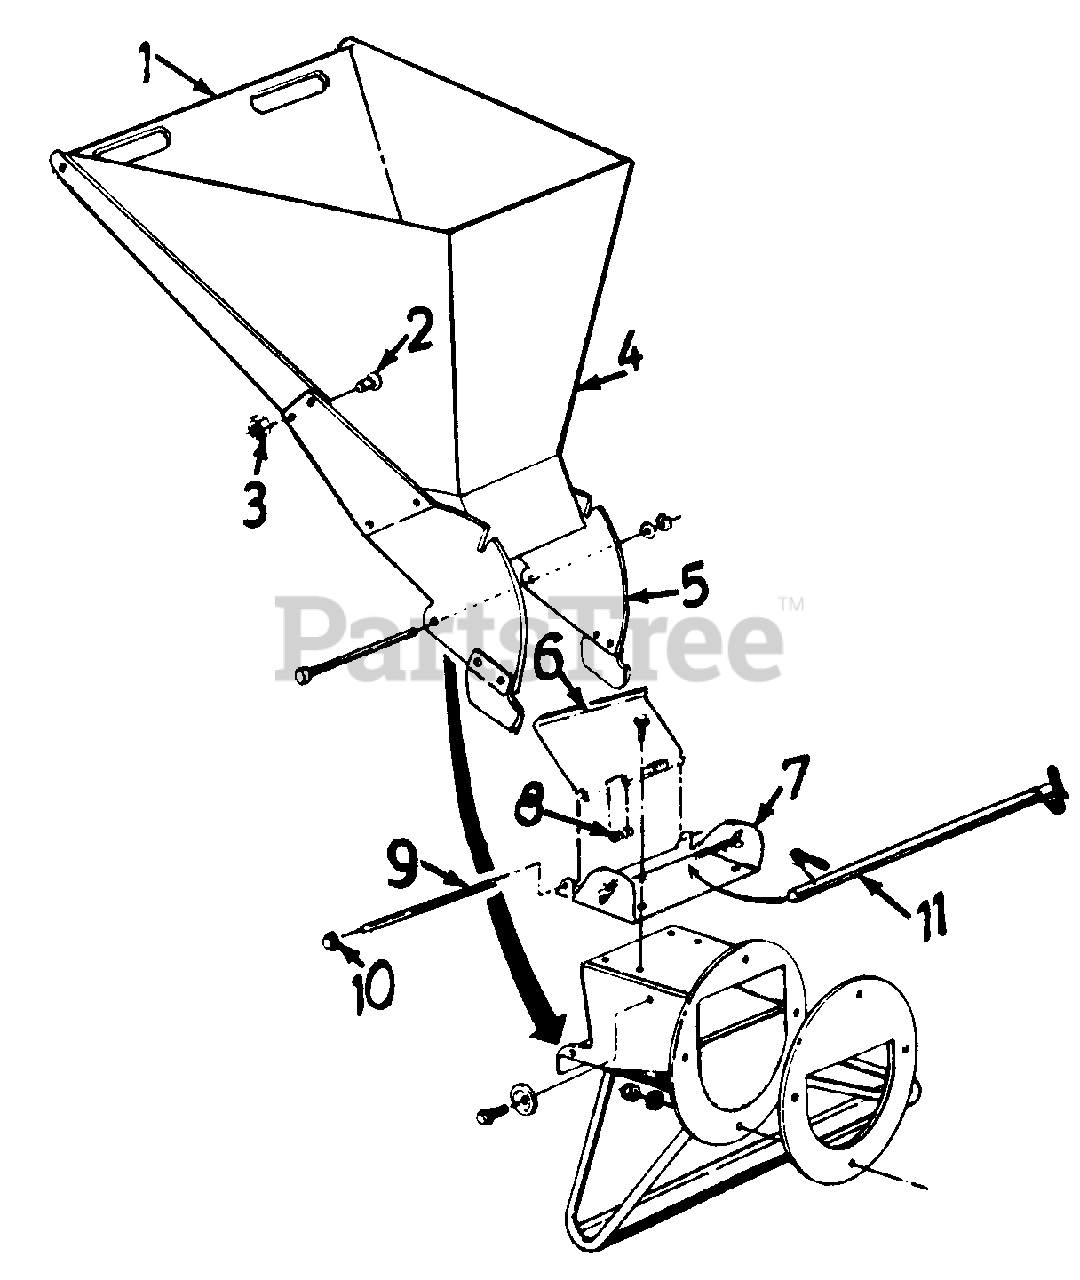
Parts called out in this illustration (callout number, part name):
3	HEX L-NUT 1/4-20 THD.
9	HOPPER DOOR ROD
10	CAP SPEED NUT 1/4" ROD
11	RELEASE BAR
